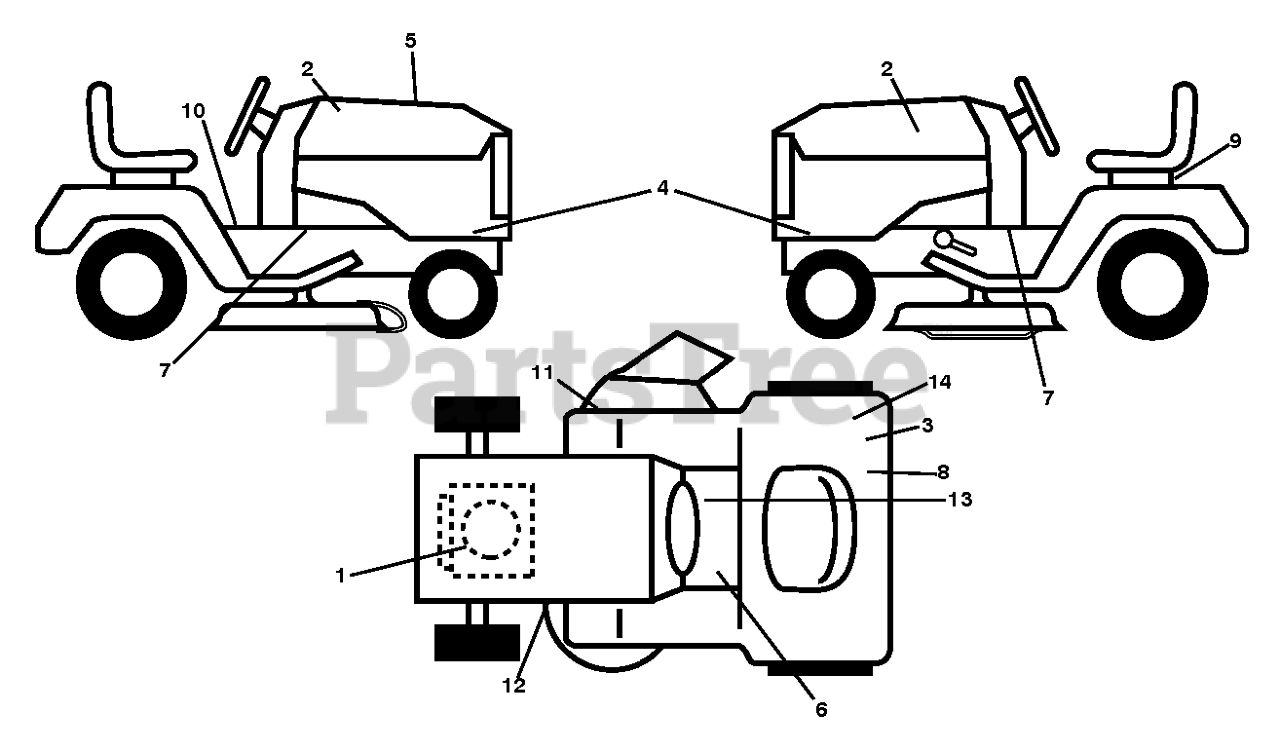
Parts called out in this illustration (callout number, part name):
1	DECAL
2	DECAL.BADGE.170MM.TEXTLOGO.
3	DECAL
4	DECAL.SDPNL.LTH19530.
6	DECAL
8	DECAL
9	DECAL BTRY SYMBOLS
10	LABEL
11	DECAL.WARN.DFLECT/CTFINGR.SRD
12	Decal, Mower V-Belt Schematic
13	DECAL PARK BRAKE
14	DECAL 80 DBA
